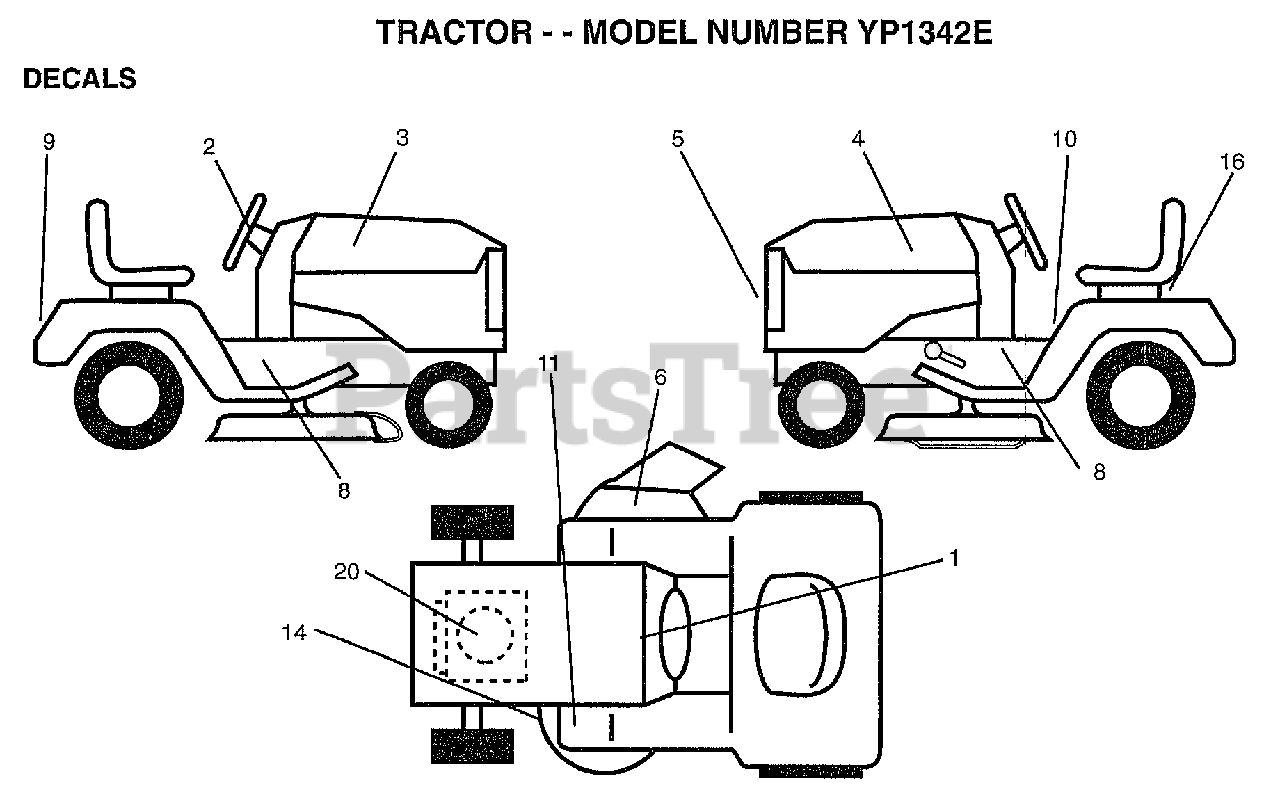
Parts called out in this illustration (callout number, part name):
1	"DECAL.OPER,SDL"
2	"DECAL INSERT,STRG"
3	DECAL.HOOD.RH
4	DECAL HOOD LH
6	"DECAL, WARNING"
8	DECAL CHASSIS
9	DECAL FENDER
10	DECAL.CAUT.ENG/FR
11	DECAL T
14	"DECAL-SCHEM,BELT"
16	DECAL.BATRY.3-3908
20	DECAL.HP.ENG.B&S13HP
